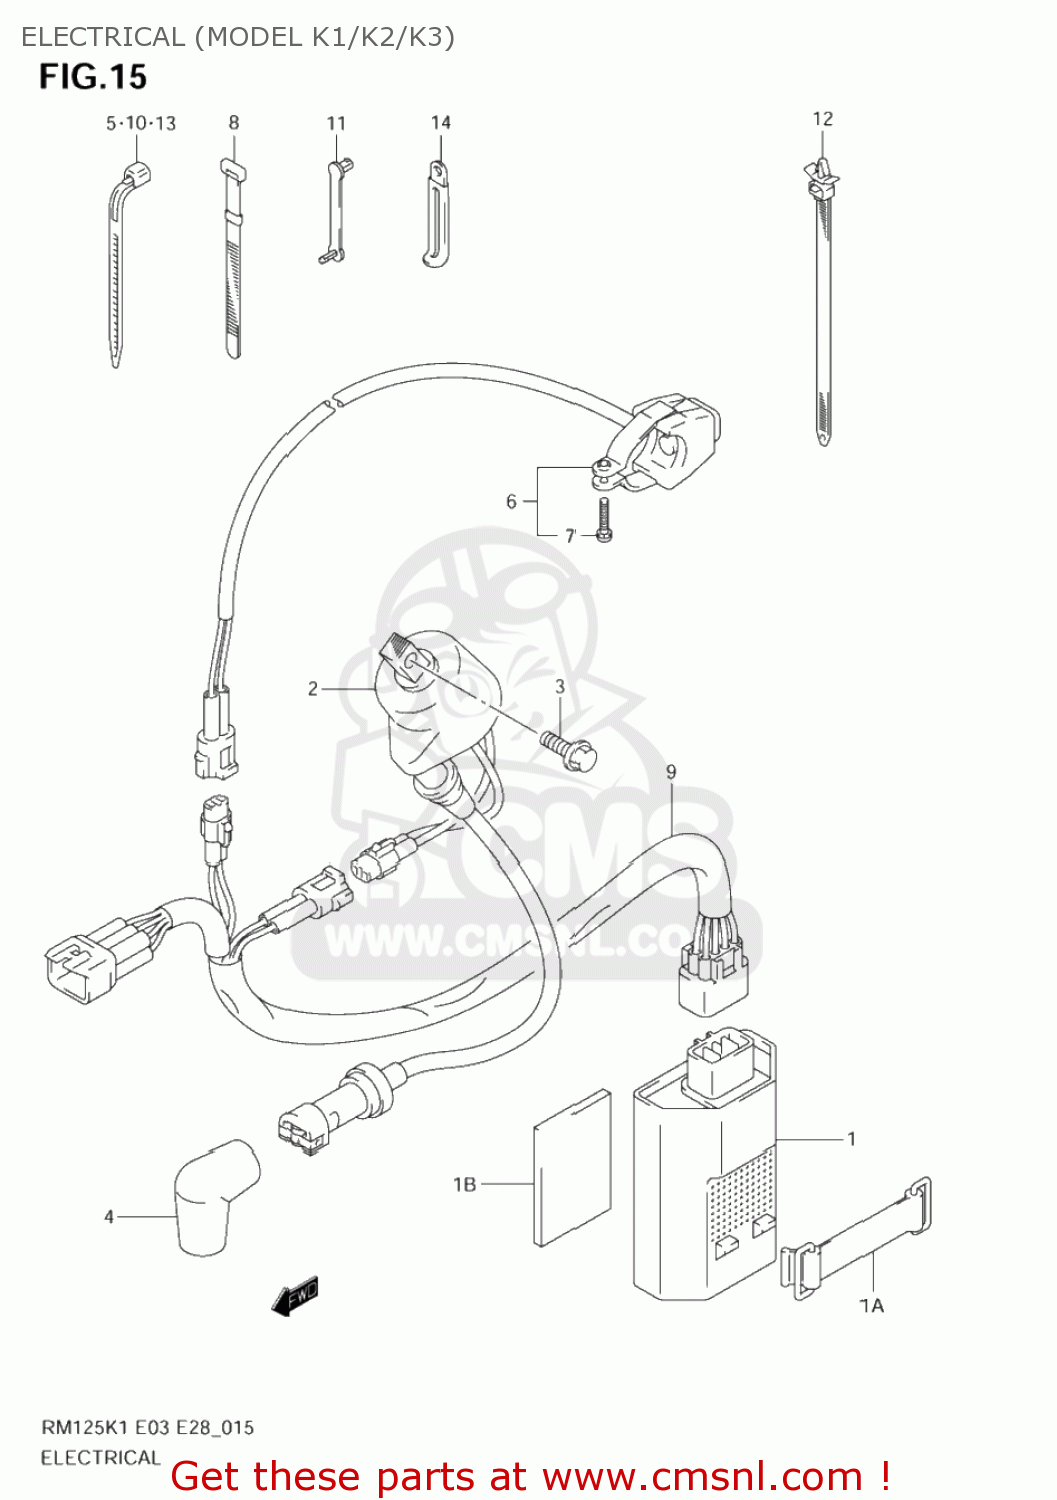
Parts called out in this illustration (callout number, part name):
1	CDI UNIT
1A	BAND,CDI UNIT(L:80)
1B	PROTECTOR(170X95X3.0)
2	COIL ASSEMBLY,IGNITION
3	BOLT
4	CAP,SPARK PLUG
5	CLAMP(L:165)
6	SWITCH ASSY,ENGINE STOP
7	SCREW
8	CLAMP(L:120)
9	HARNESS,WIRING
10	CLAMP(L:235)
11	CLAMP(L:63)
12	CLAMP(L:90)
13	CLAMP(L:125)
14	CLAMP(L:65)
